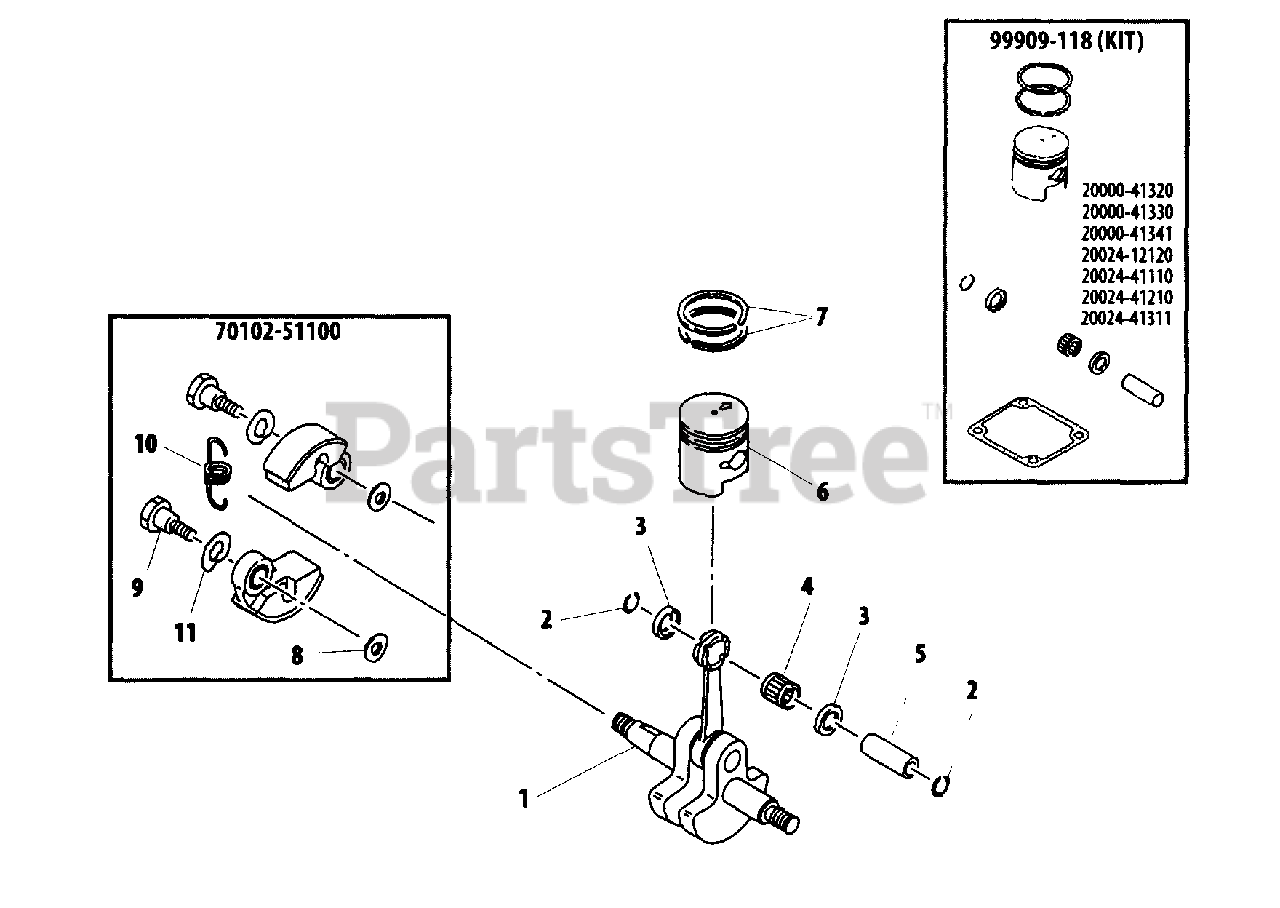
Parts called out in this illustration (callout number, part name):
1	CRANKSHAFT ASSY
2	RING, SNAP
3	WASHER, THRUST - 9
4	BEARING, NEEDLE
5	PIN, PISTON
6	PISTON
7	RING, PISTON
8	WASHER 6 MM
9	BOLT, CLUTCH
10	SPRING, CLUTCH
11	WASHER, SPRING
70102-51100	CLUTCH ASSY
99909-118	PISTON ASSY
